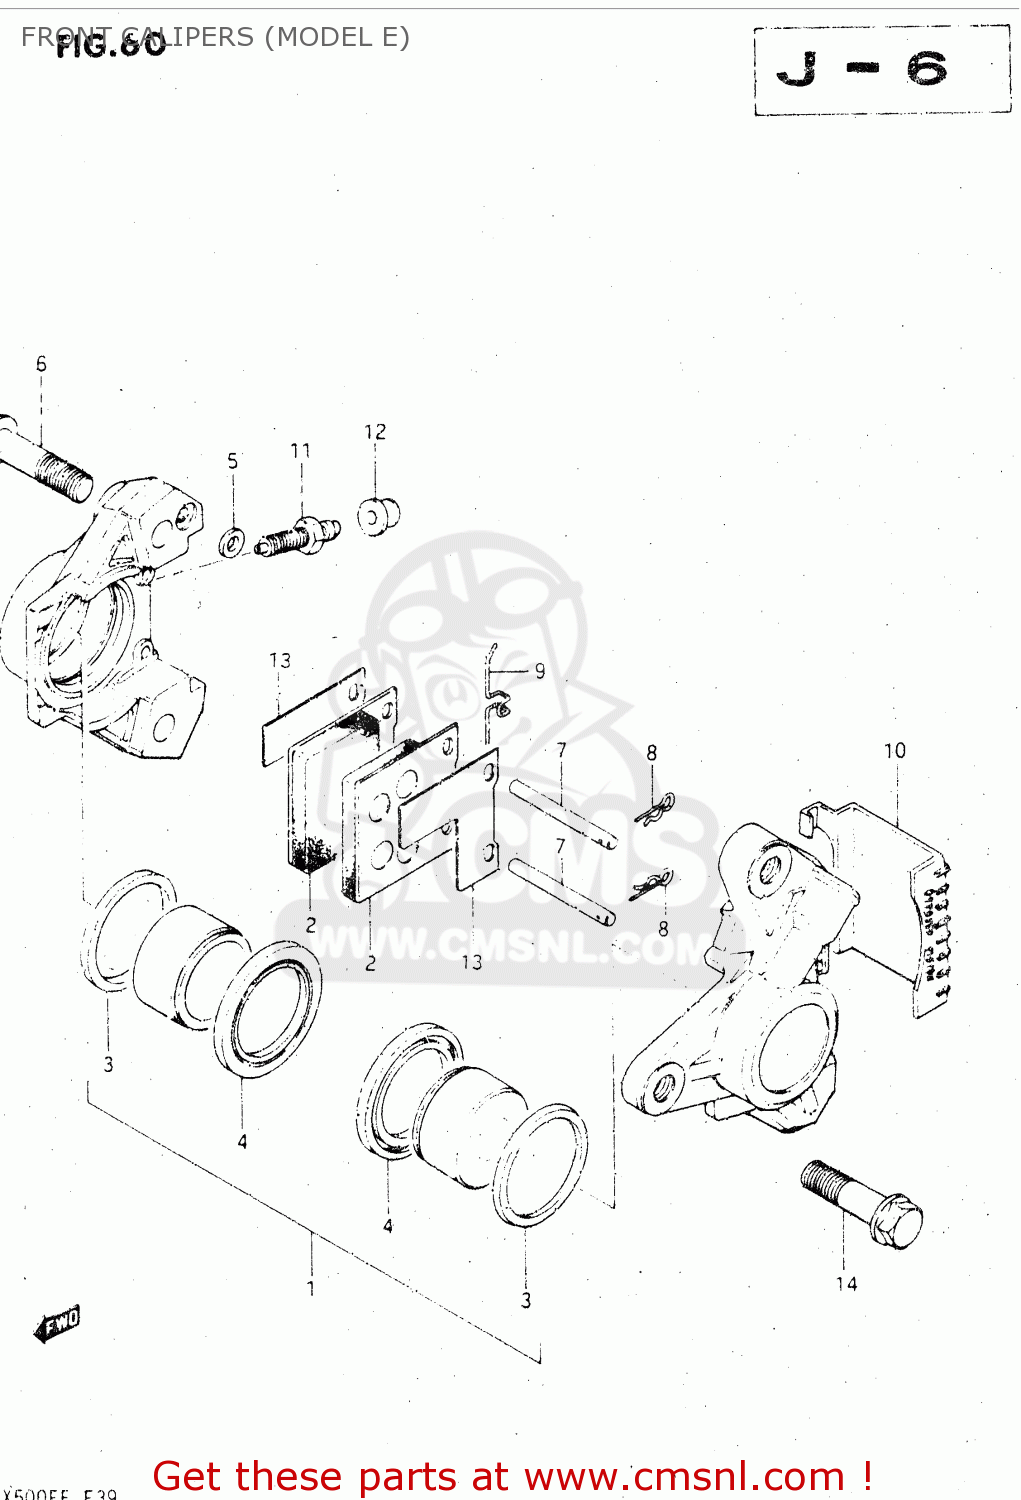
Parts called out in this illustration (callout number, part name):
1	PISTON SET
2	PAD (MCA)
3	SEAL,PISTON
4	BOOT
5	SEAL,JOINT
6	BOLT,HOUSING
7	PIN,PAD
8	CLIP,PAD PIN
9	SPRING
10	COVER,CALIPER
11	BLEEDER
12	CAP,BREATHER
13	SHIM
14	BOLT 10X37
